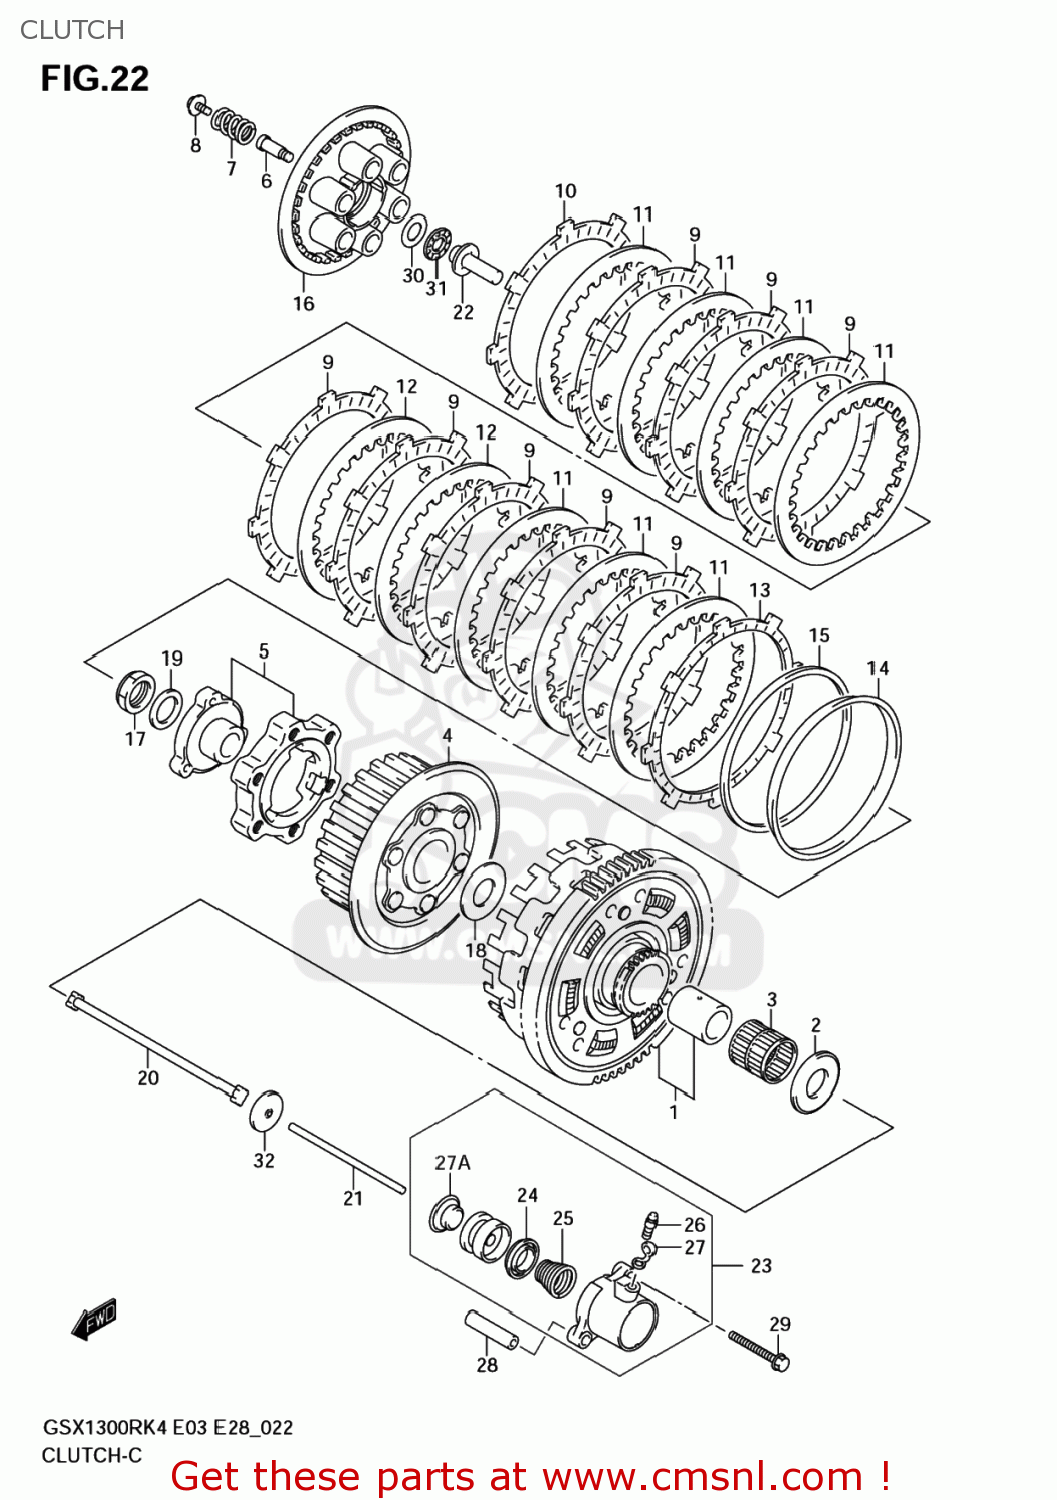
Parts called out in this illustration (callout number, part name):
1	GEAR ASSY,PRI DRIVEN
2	WASHER(25X54X2.5)
3	BEARING(35X40X39.8)
4	HUB,CLUTCH SLEEVE
5	CAM SET,CLUTCH
6	BOLT,CLUTCH SPRING SUPPORT
7	SPRING CLUTCH
8	BOLT,CLUTCH SPRING
9	PLATE,CLUTCH DRIVE NO.1 (NAS)
10	PLATE,CLUTCH DRIVE NO.2 (NAS)
11	PLATE,CLUTCH DRIVEN NO.1(T:2.0 (NAS)
12	PLATE,CLUTCH DRIVEN NO.2(T:2.3 (NAS)
13	PLATE,CLUTCH DRIVE NO.3 (NAS)
14	SEAT,WAVE WASHER
15	WASHER,CLUTCH PLATE WAVE
16	DISC,CLUTCH PRESSURE
17	NUT
18	WASHER(25X50X2.5)
19	WASHER
20	ROD,CLUTCH
21	ROD,CLUTCH PUSH,L
22	PIECE,CLUTCH PUSH
23	CYLINDER,CLUTCH RELEASE
24	CUP
25	SPRING,CLUTCH CYLINDER
26	BLEEDER
27	CAP,BLEEDER
27A	COVER,DUST
28	PIN
29	BOLT
30	WASHER(15.5X28X1)
31	BEARING(15X28X2)
32	SEAL,OIL(6X34X5.5)
